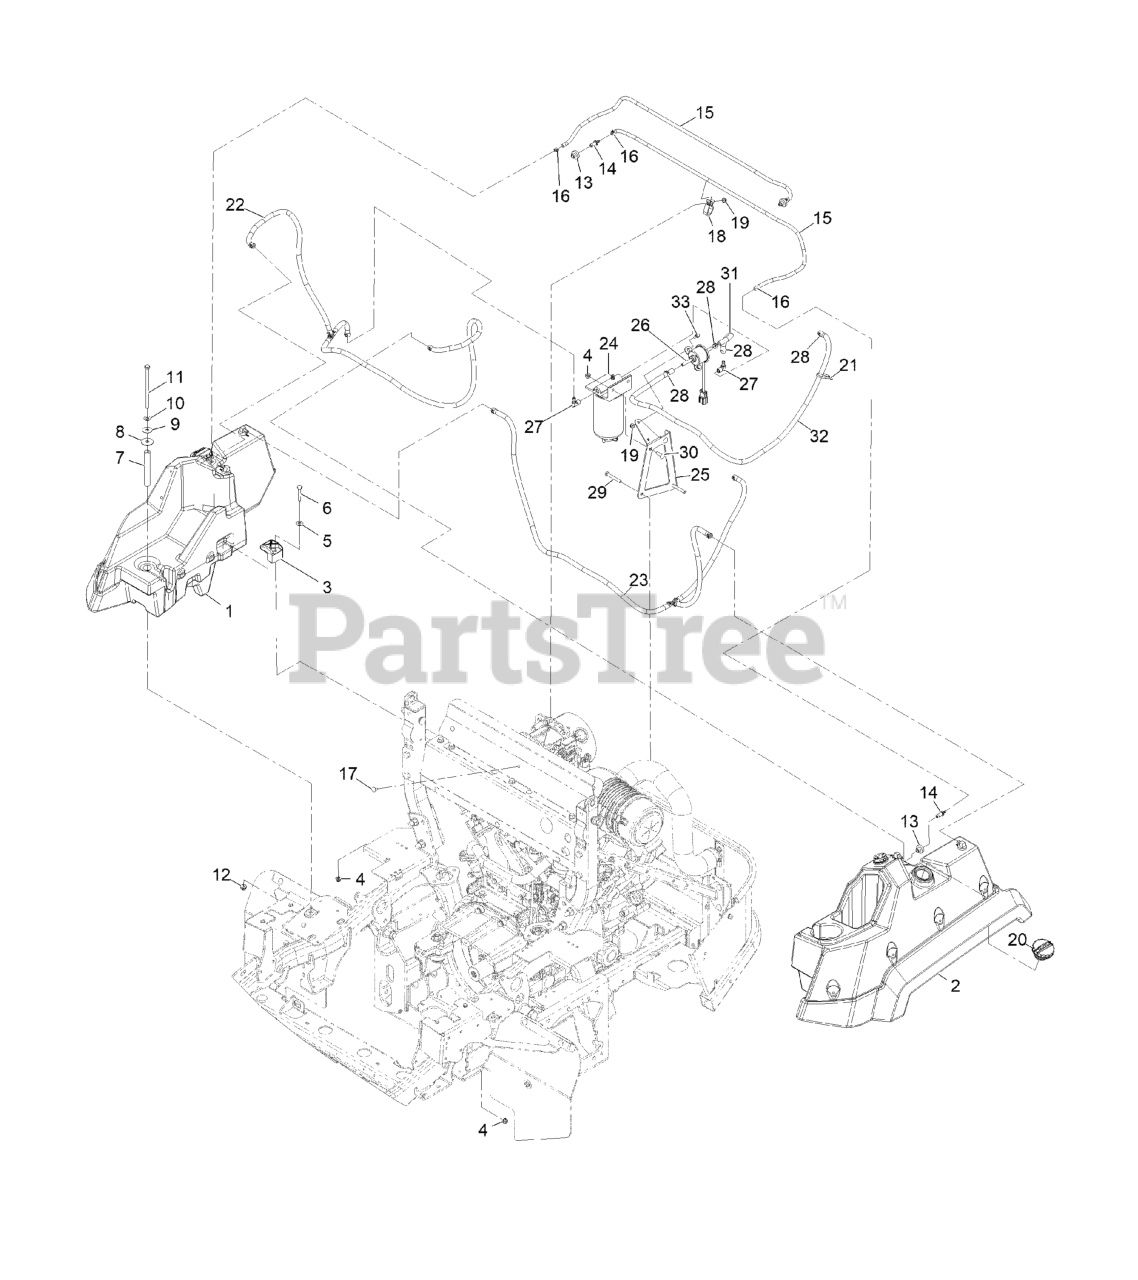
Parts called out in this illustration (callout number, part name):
1	RH FUEL TANK ASM
2	LH FUEL TANK ASM
4	NUT-HF, NI
5	WASHER-FLAT
6	SCREW-HH
7	TUBE-SPACER
8	WASHER-RUBBER
9	WASHER-PLAIN
10	WASHER-FLAT
11	SCREW-HH
12	NUT-HF, NI
13	BUSHING
14	FITTING-ORIFICE, STRAIGHT
15	HOSE-VENT, TANK
16	CLAMP-HOSE
17	SCREW-CARR
18	CLAMP-HOSE
20	CAP-FUEL, DIESEL
21	TIE-CABLE
22	FUEL SUCTION LINE ASM
23	FUEL RETURN LINE ASM
24	FILTER-WATER/FUEL SEPERATOR
25	BRACKET-FILTER, FUEL
26	PUMP-FUEL, ELECTRIC
27	FITTING-HYD, 90
28	CLAMP-HOSE
29	SCREW-HH
30	SCREW-CARR
31	HOSE-FUEL
32	HOSE-FUEL
33	SCREW-HWH
